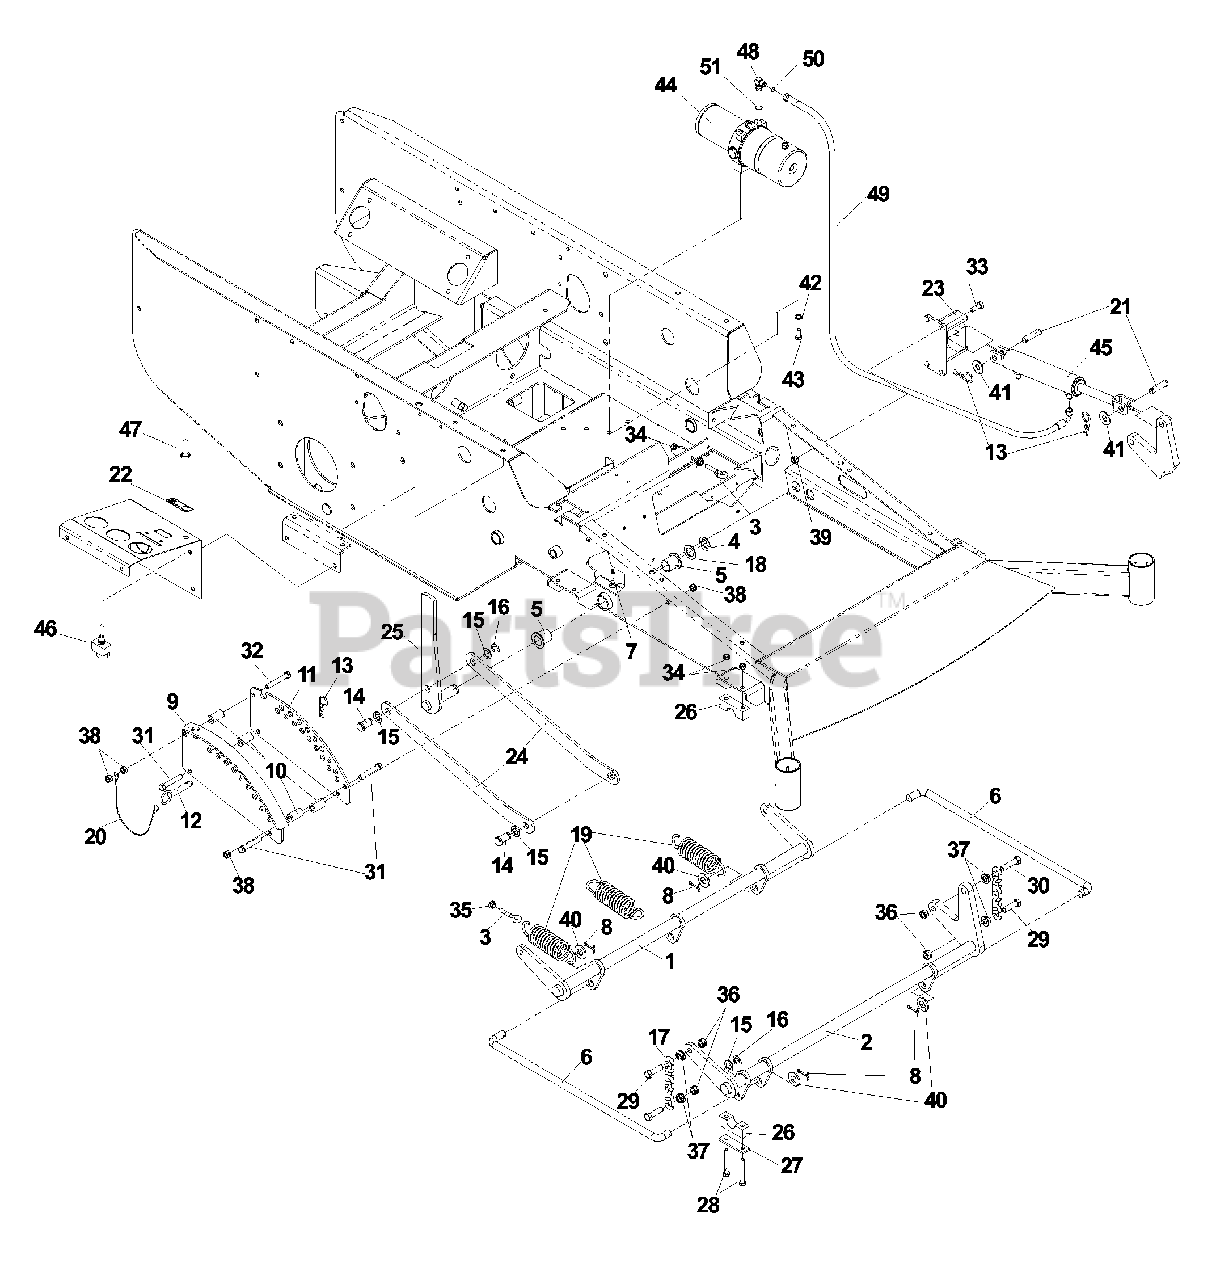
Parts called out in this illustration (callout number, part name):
1	Shaft, lift, rear
2	Shaft, lift, front
3	Eyebolt, right
4	E-ring, 7/8
5	Bushing, flanged-PM
6	Link, connecting
7	Zerk, long
8	Pin, cotter, 5/32 x 1 1/4
9	Adjustment plate
11	Adjustment plate
13	Hairpin, #4
14	Pin, clevis
15	Bushing, machine, 5/8
16	E-ring, 5/8
17	Lift chain
18	Bushing, machine, 7/8
19	Spring, extension
21	Pin, clevis, 1/2 x 1 3/4
22	Decal, lift switch
23	Cylinder mounting
24	Lift linkage
25	Lift lever
26	Pillow block
27	Bar, reinforcement
28	Bolt, 5/16-18 x 2 1/2
29	Bolt, 7/16-14 x 1 1/2
30	Bolt, 7/16-14 x 1 3/4, GR 5
31	Bolt, 3/8-16 x 2 1/4
32	Bolt, 3/8-16 x 2 1/2
33	Bolt, 3/8-16 x 1
34	Nut, 5/16-18, centerlock
35	Nut, 5/16-18, serrated washer
36	Nut, 7/16-14, centerlock
37	Nut, 7/16-14, whiz
38	Nut, 3/8-16, centerlock
39	Nut, 3/8-16, nyloc
40	Washer, 5/8
41	Washer, 1/2
42	Lockwasher, 3/8
43	Bolt, 3/8-16 x 3/4
44	Power unit/hydraulic lift
47	Switch boot
49	Hose assembly
